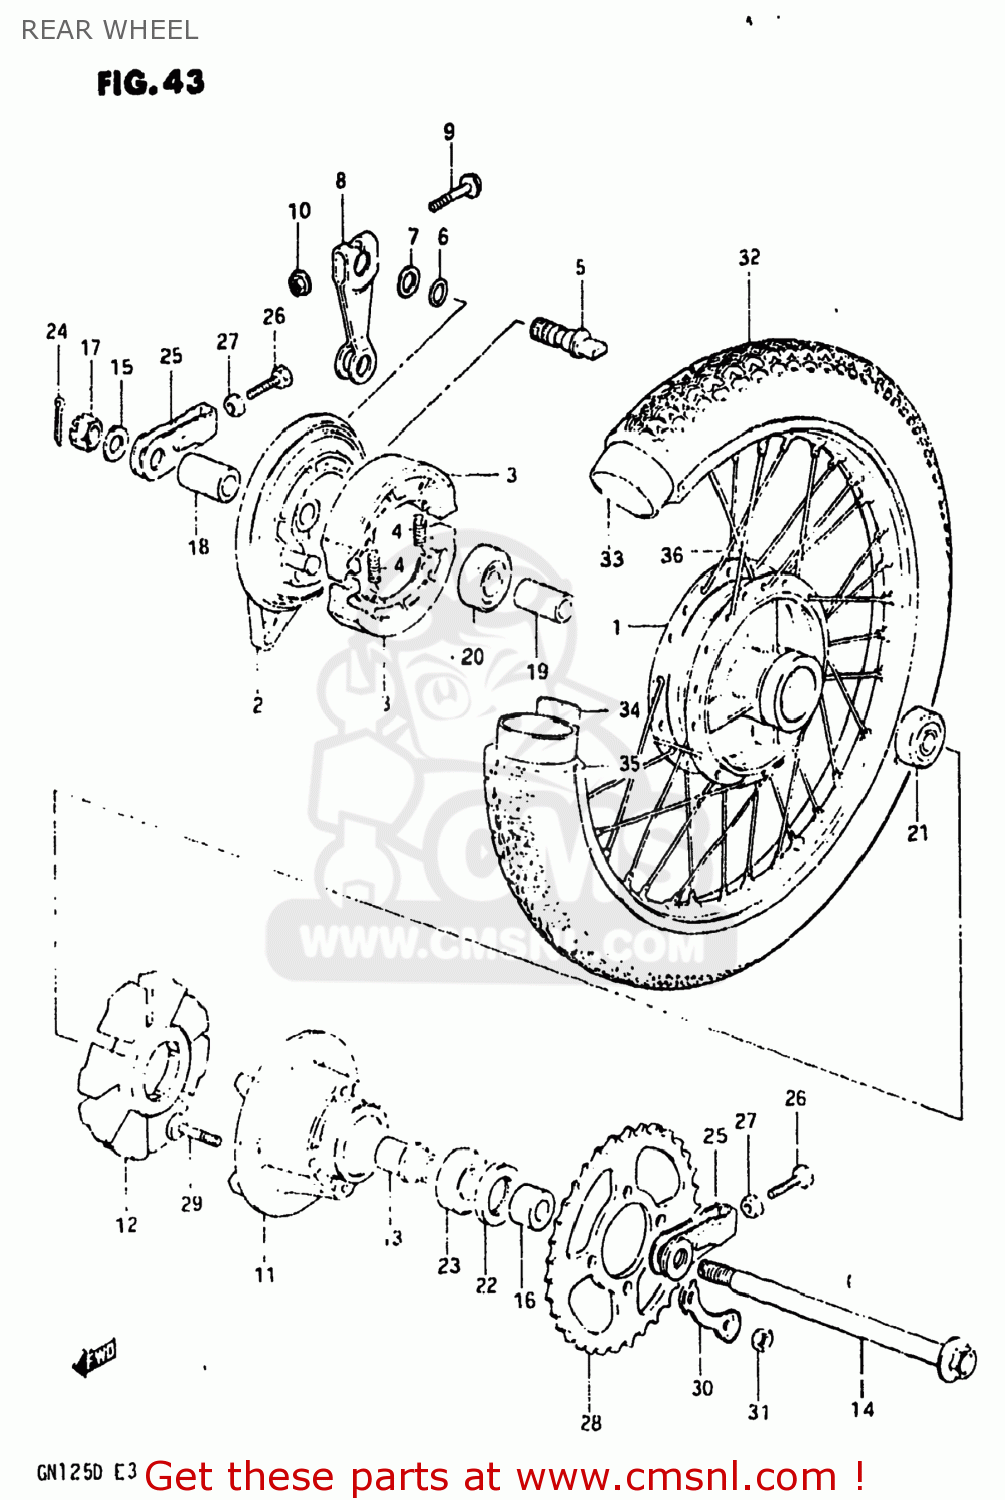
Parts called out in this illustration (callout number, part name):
1	HUB,REAR WHEEL
2	PANEL,REAR BRAKE ANCHOR
3	SHOE,BRAKE
4	SPRING(L:34)
5	CAM,FRONT BRAKE
6	O-RING (D:2.4 ID:13.8)
7	WASHER (14.5X22X1.6)
8	LEVER,RR BRAKE CAM
9	BOLT 6X35
10	NUT
11	DRUM,REAR SPROCKET MOUNT
12	ABSORBER ASSY,HUB SHOCK
13	RETAINER,RR SPROCKET DRUM
14	AXLE,REAR
15	WASHER
16	SPACER(15X28X19)
17	NUT
18	SPACER(15.2X26X33)
19	SPACER(15.3X21.7X63)
20	BEARING
21	BEARING
22	SEAL,OIL(28X47X7)
23	Bearing
24	COTTER PIN
25	ADJUSTER,CHAIN
26	BOLT
27	NUT
28	SPROCKET,REAR
29	BOLT
30	WASHER
31	NUT
32	TIRE
33	TUBE
34	PROTECTOR,WHEEL,INNER
35	RIM,RR WHEEL(185X16)
36	SPOKE SET,REAR WHEEL
